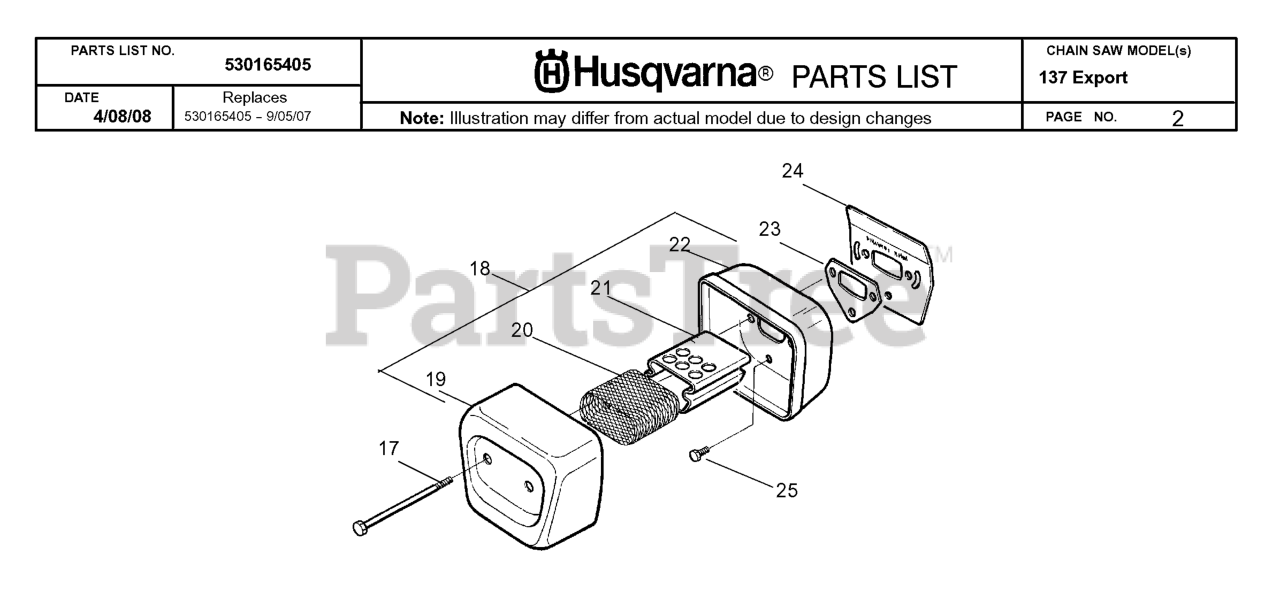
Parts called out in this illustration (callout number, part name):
18	MUFFLER KIT
19	SILENCER COVER
20	SPARK ARRESTOR 36/41
21	FLAME PROTECTOR
22	SILENCER BODY
24	MUFFLER PLATE
25	BOLT-MUFFLER(SUPPORT)
